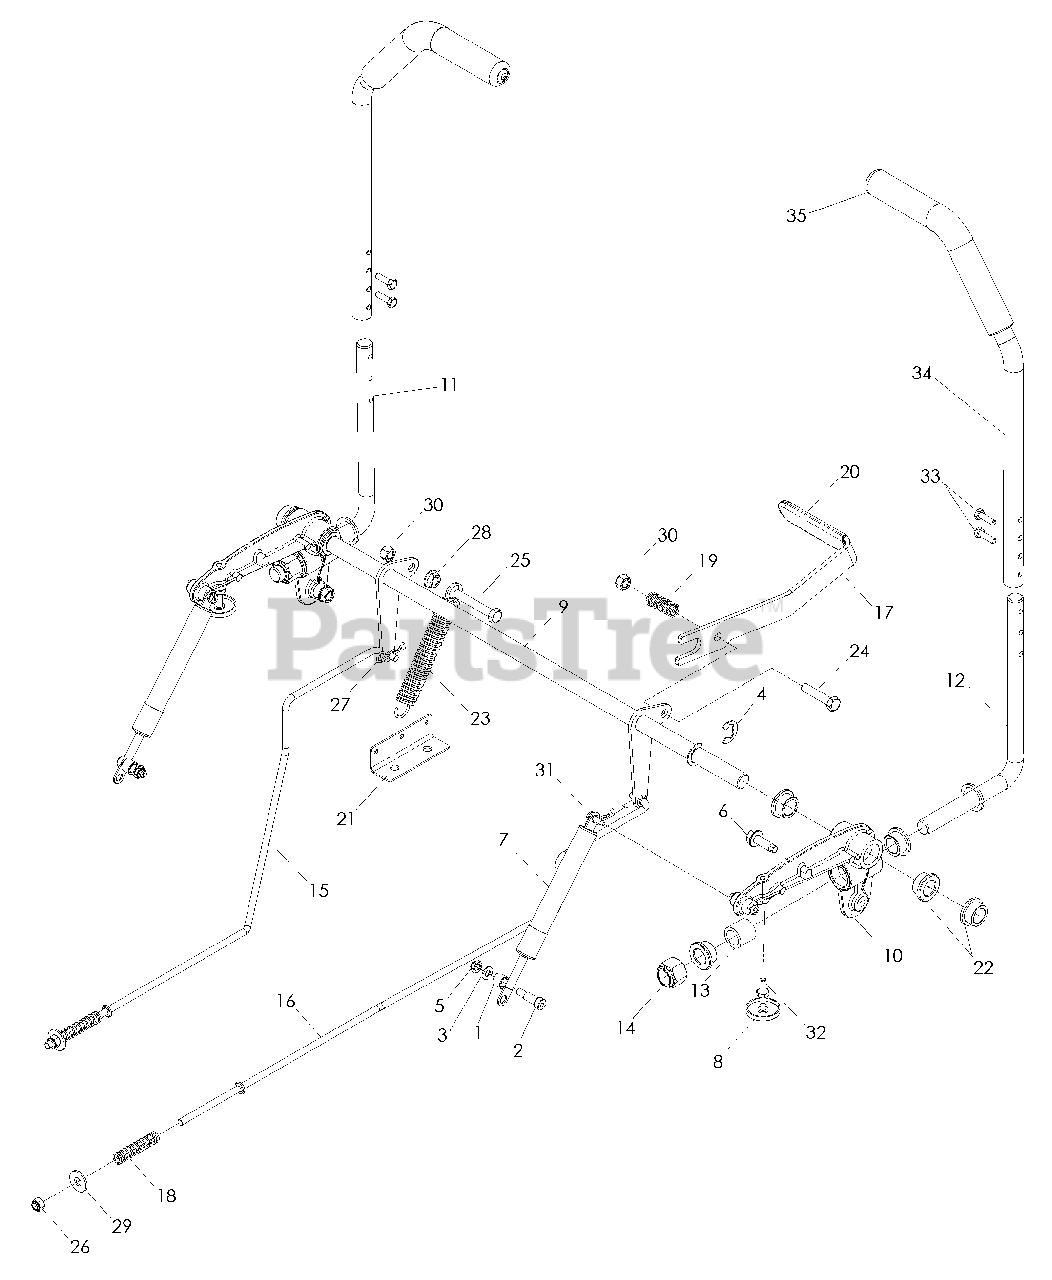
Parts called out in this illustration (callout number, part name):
2	BOLT, 5/16-18 x 5/8, SKT HD
3	WASHER, 1/4
4	RING-E, 5/8
5	NUT, 1/4-20, THIN, NYLOC
6	BOLT, 5/16-18 x 1 1/4
8	POST, RETURN
9	SHAFT, MOTION
10	MOTION CASTING
11	MOTION CONTROL ARM, LT
12	MOTION CONTROL ARM, RT
14	NUT, 5/8-11, NYLOC
15	BRAKE ROD, RT
16	BRAKE ROD, LT
17	BRAKE LEVER
19	SPRING, BRAKE LEVER
20	CAP, BRAKE LEVER
21	SPRING BRACKET
22	MOTION BUSHING
23	SPRING, TRANS
24	HCS, 5/16-18 x 1 1/2
25	HCS, 5/16-18 x 2
26	NUT, 1/4-20, NYLOC
27	PIN HAIR, .073 x 17/16
28	NUT, 5/16-18, WHIZLK
29	WASHER, 5/16
30	NUT, 5/16-18, NYLOC
31	SCRW, #10-24 x 5/8, WSH HD
32	NUT, 1/4-20, JAM
33	HCS, 1/4-20 x 7/8
34	CONTROL LEVER
35	GRIP, CONTROL LEVER
